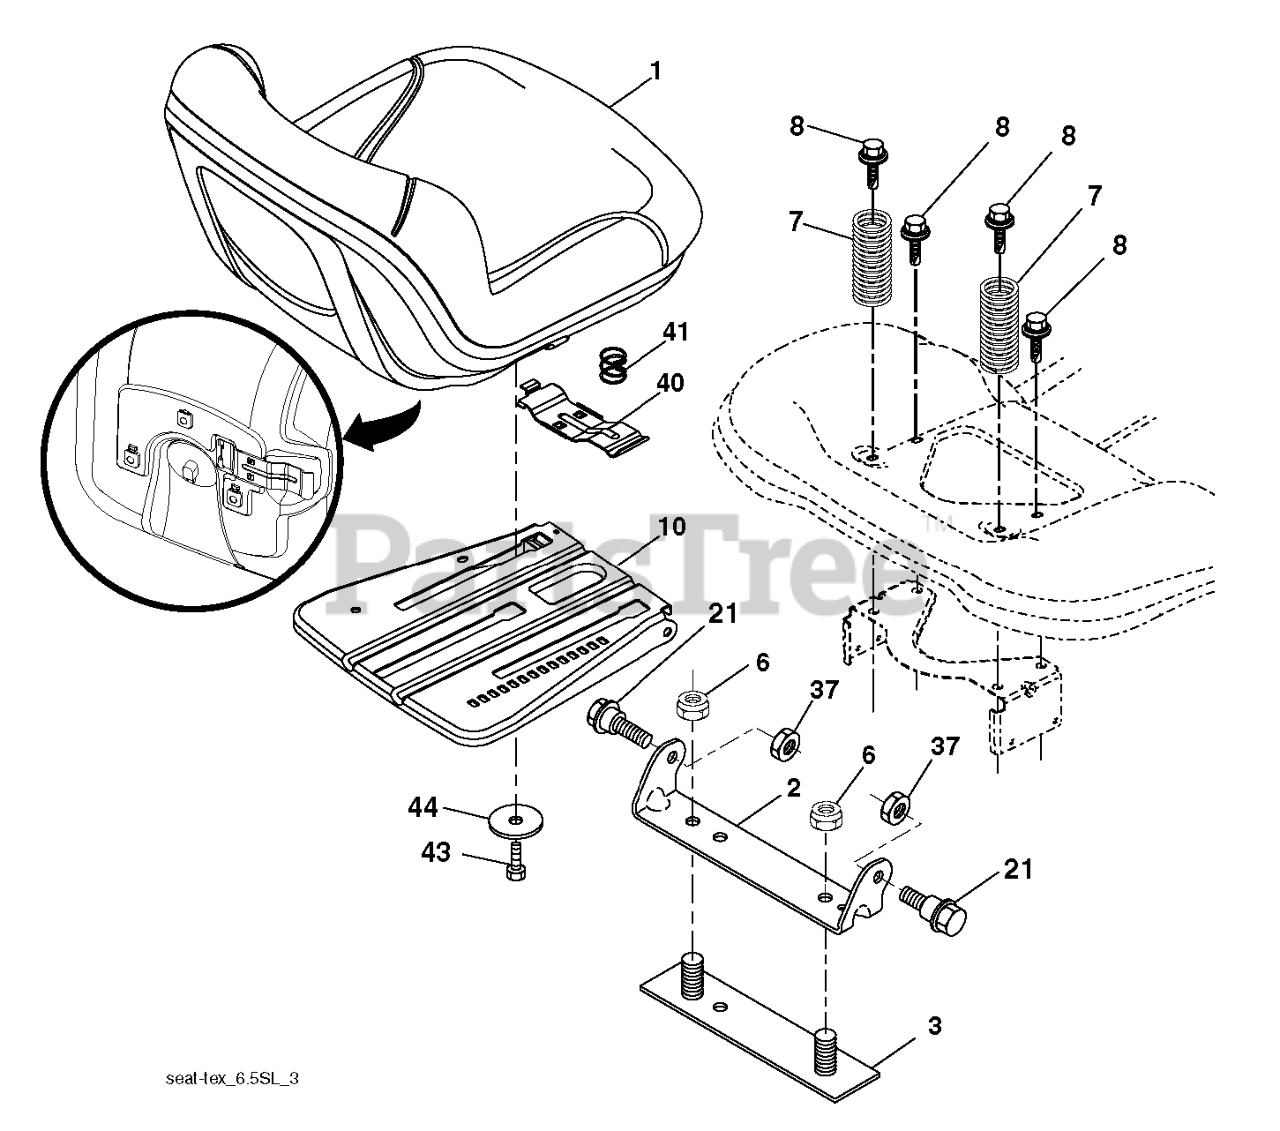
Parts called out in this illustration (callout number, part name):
1	RP SEAT, TH150, GREY, MILSCO
2	BRKT.PIVOT.FENDER
3	STRAP
6	NUT
7	SPRING COMPRESSION
8	BOLT.5/16-18UNCX3/4 W/SEMS.BLK
10	PAN.ASM.SEAT.3PT
21	BOLT.SHOULDER.5/16-18
37	NUT.71038.31-18.HEX.NYLOCK
40	HANDLE.SLIDE.SEAT.TEX.BLACK
41	SPRING.LATCH.SEAT.TEX
44	WASHER 13/32 X 2-3/8 X 12GA
